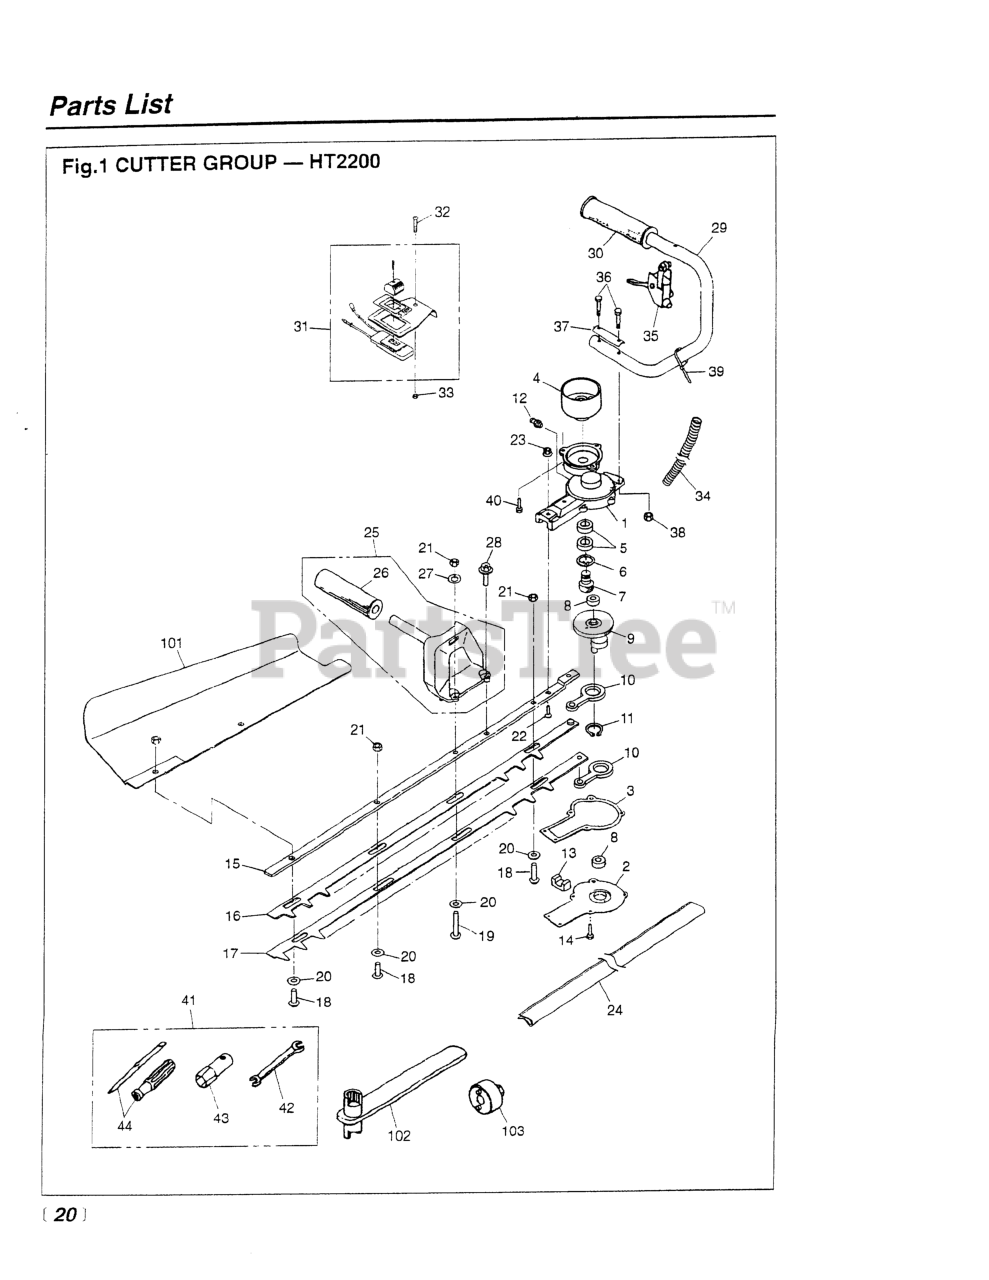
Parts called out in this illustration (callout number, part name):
1	GEARCASE
2	COVER
3	GASKET
4	DRUM, CLUTCH
5	BEARING
6	RING, SNAP
7	PINION
9	GEAR COMPL
10	ROD
11	RING, SNAP, M25 X 1.2
12	FITTING, GREASE
13	FELT
14	BOLT
15	PLATE, GUIDE
16	BLADE, UPPER
17	BLADE, LOWER
20	WASHER (RPLS 3873-11760)
21	NUT, M6
22	SCREW
23	NUT
24	COVER, BLADE
25	HANDLE COMPL
26	GRIP (RPLS -13120)
28	BOLT
29	HANDLE COMP.
30	GRIP (RPLS -13120)
33	NUT (M5X0.8)
34	TUBE
35	LEVER ASSEMBLY
38	NUT (RPLS 3873-14470)
39	BAND, CABLE
41	TOOL SET
42	SPANNER, 8 X 10 (RPLS 2540- )
43	SOCKET, HEX, 3/4
44	SCREWDRIVER
101	RECEIVE PLATE
103	WRENCH (TOOL)
